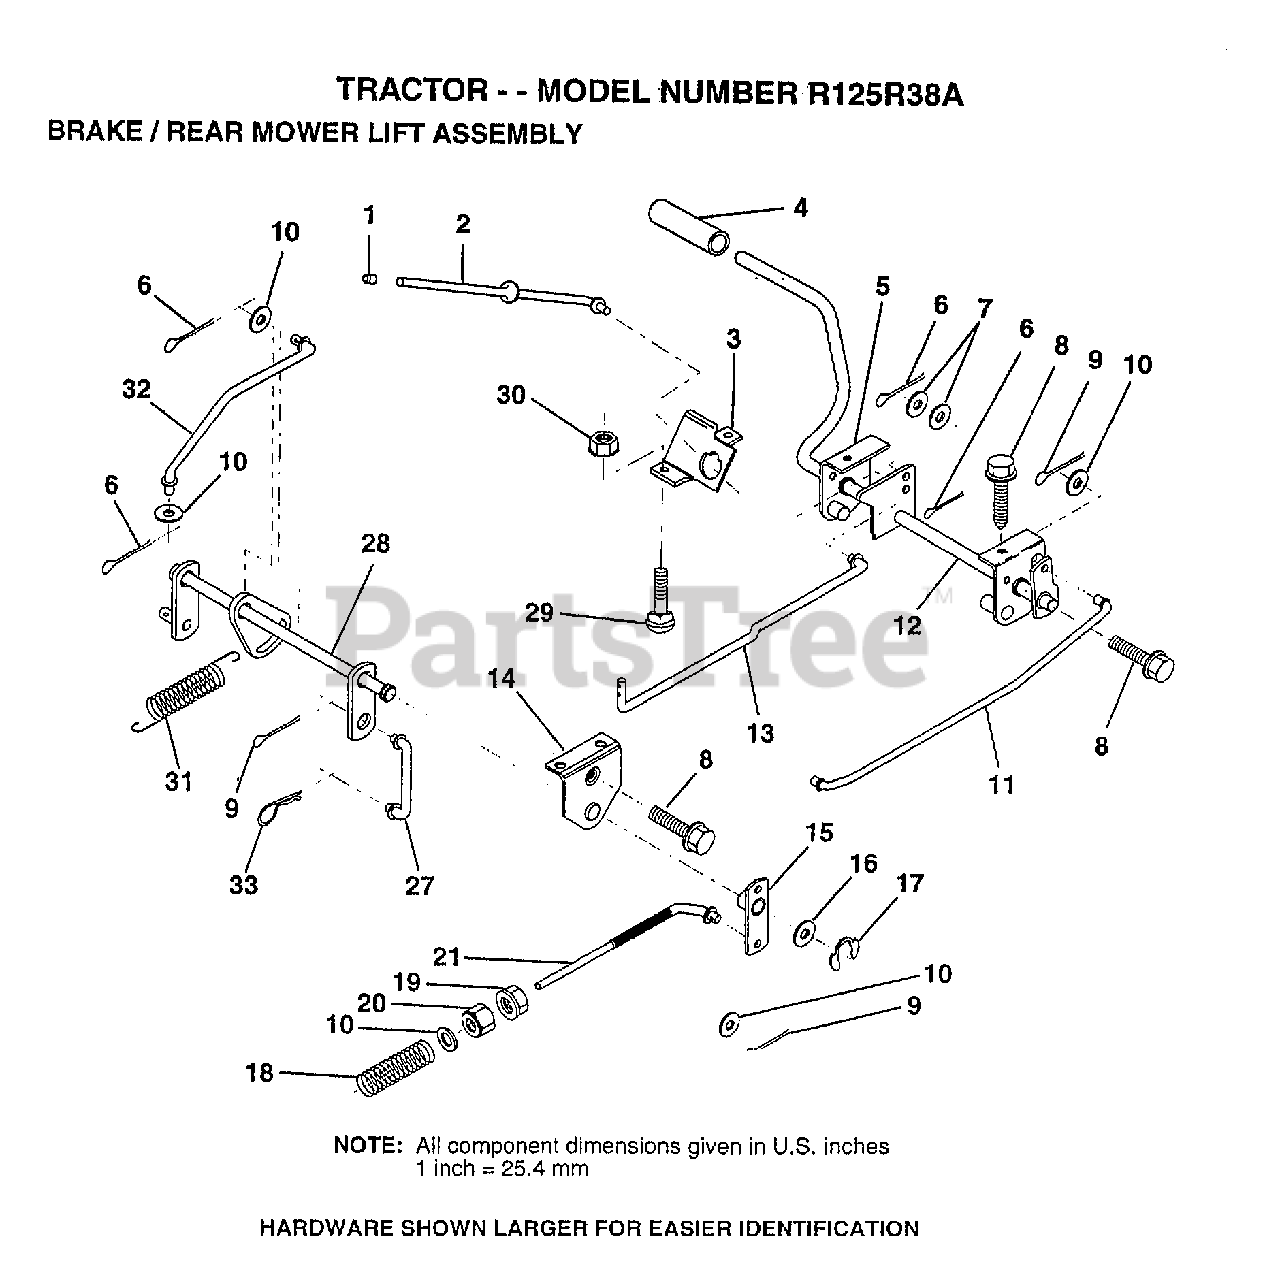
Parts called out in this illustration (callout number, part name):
1	PLUNGER CAP T
2	"ROD,PARK BRAKE"
3	"BRKT,PARK BRAKE"
4	FOOT PEDAL COVER
5	BRK ASM CLUT LH
7	WASHER
8	SCREW LT
9	COTTER PIN
10	WASHER
12	PEDAL ASM CLU/BRK
13	"ROD,CLUTCH"
14	"BRKT,LIFT SHAFT"
15	PVT BRAKE ARM ASM
16	WASHER T
17	KLIP RING
18	SPRING ROD BRAKE
19	NUT
20	NUT
27	LINK LIFT REAR LR
28	LIFT.ASM.REAR.LR
31	COUNTER SPRING
32	LINK LIFT LEVER
